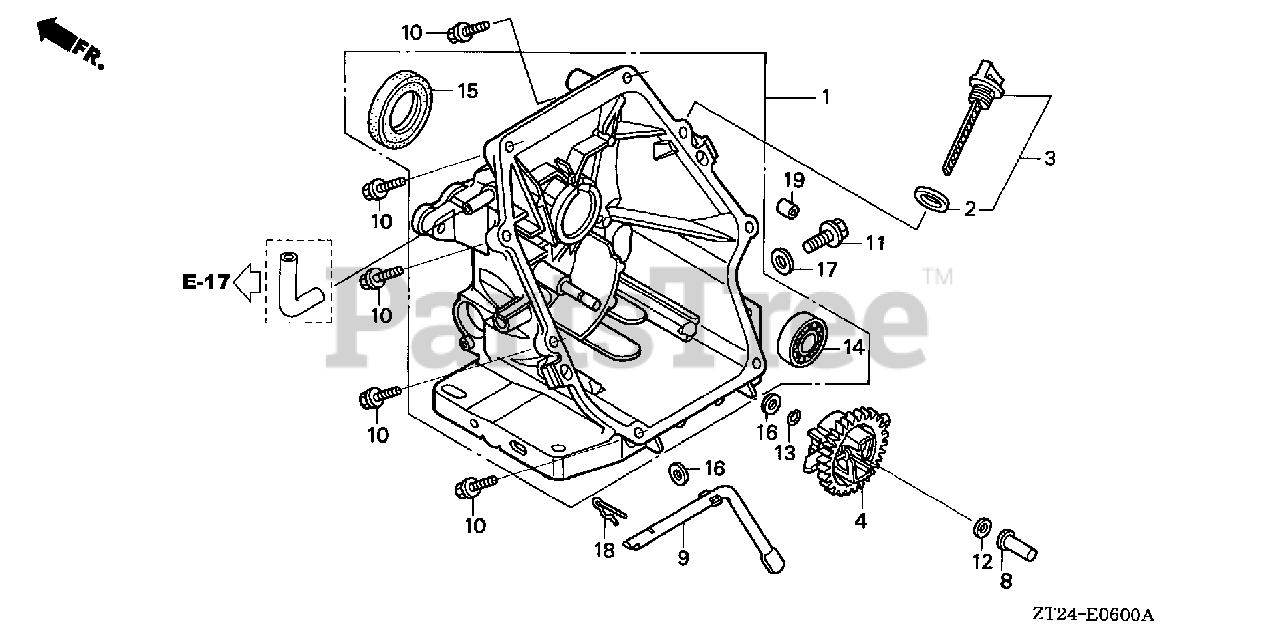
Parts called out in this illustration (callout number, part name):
1	COVER ASSY., CRANKCASE
2	GASKET, OIL FILLER CAP
3	GAUGE ASSY., OIL LEVEL
4	GOVERNOR ASSY.
8	SLIDER, GOVERNOR
9	SHAFT, GOVERNOR ARM
10	BOLT, FLANGE (6X25) (CT200)
11	BOLT, DRAIN PLUG (12X15)
12	WASHER, THRUST (6MM)
13	CLIP, GOVERNOR HOLDER
14	BEARING, RADIAL BALL (62/28)
15	OIL SEAL (28X41.25X6)
16	WASHER, PLAIN (6MM)
17	WASHER, DRAIN PLUG (12MM)
18	PIN, LOCK (8MM)
19	PIN, DOWEL (8X20)
